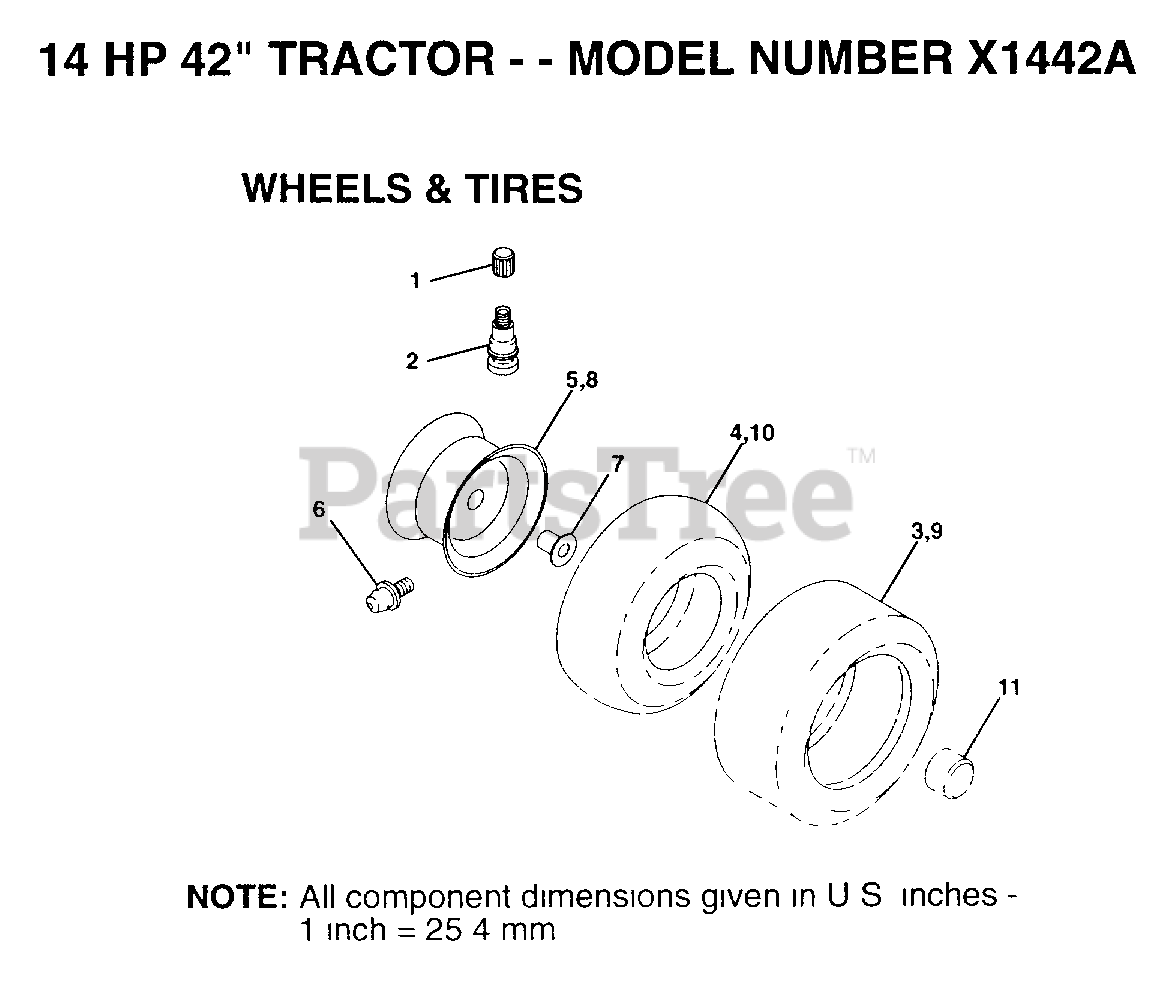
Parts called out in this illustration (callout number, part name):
1	VALVE CAP
2	VALVE STEM LT
4	TUBE.5.3/4.5/6
6	FITTING LT
7	"FLANGE, BEARING"
9	TIRE.20X8-8
10	TUBE.18X9.5-8
11	HUB CAP
